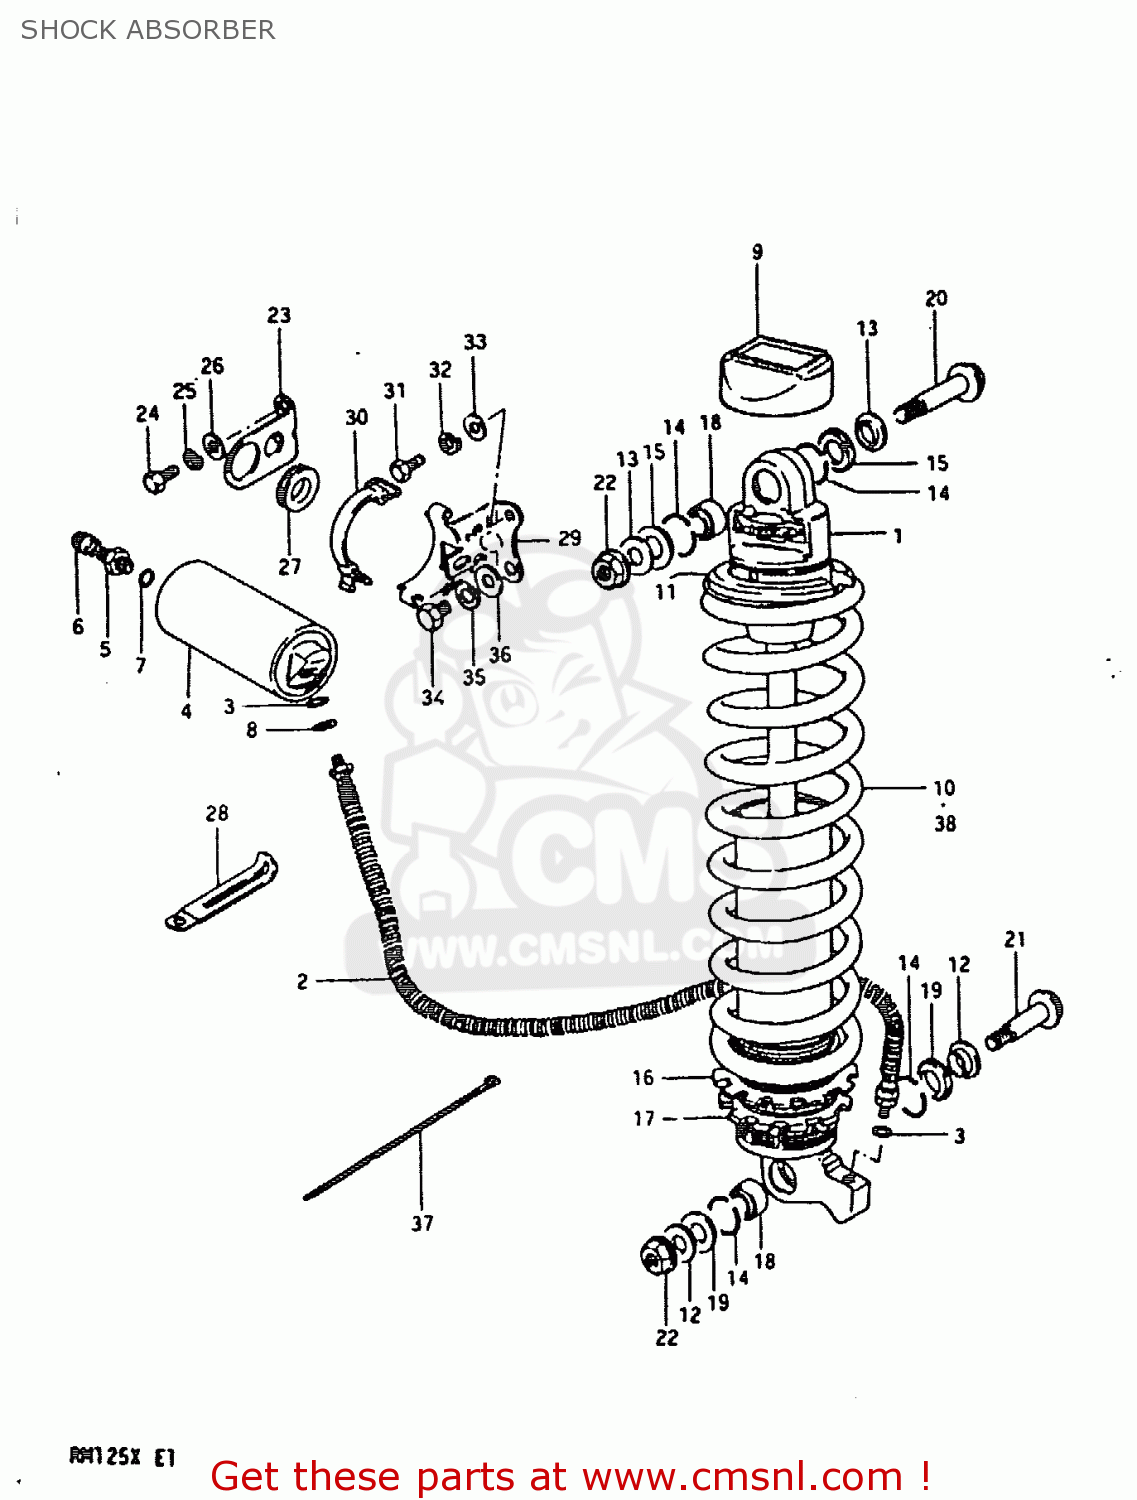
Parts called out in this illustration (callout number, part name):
1	ABSORBER ASSEMBLY,REAR SHOCK
2	HOSE,REAR SHOCK ABSORBER
3	O-RING,RESERVE TANK
4	RESERVE TANK,REAR SHOCK
5	VALVE ASSEMBLY,REAR CUSHION
6	CAP,VALVE AIR
7	O RING
8	WASHER,REAR SHOCK HOSE
9	CAP REAR SHOCK
10	SPRING
11	SPRING, GUIDE
12	COLLAR
13	SPACER,REAR SHOCK,UPPER
14	RING
15	DUST SEAL,UPR
16	GUIDE,SPRING
17	GUIDE,REAR SHOCK ABSORBER SPRING
18	BEARING
19	DUST SEAL,LWR
20	BOLT
21	BOLT(10X54)
22	NUT
23	BRACKET,RESERVOIR TANK
24	BOLT
25	LOCK WASHER
26	WASHER
27	CUSHION,RESERVOIR TANK
28	CLAMP
29	BRACKET,RESERVOIR TANK
30	BAND
31	BOLT
32	LOCK WASHER
33	WASHER
34	BOLT
35	LOCK WASHER
36	WASHER
37	CLAMP
38	SPRING
